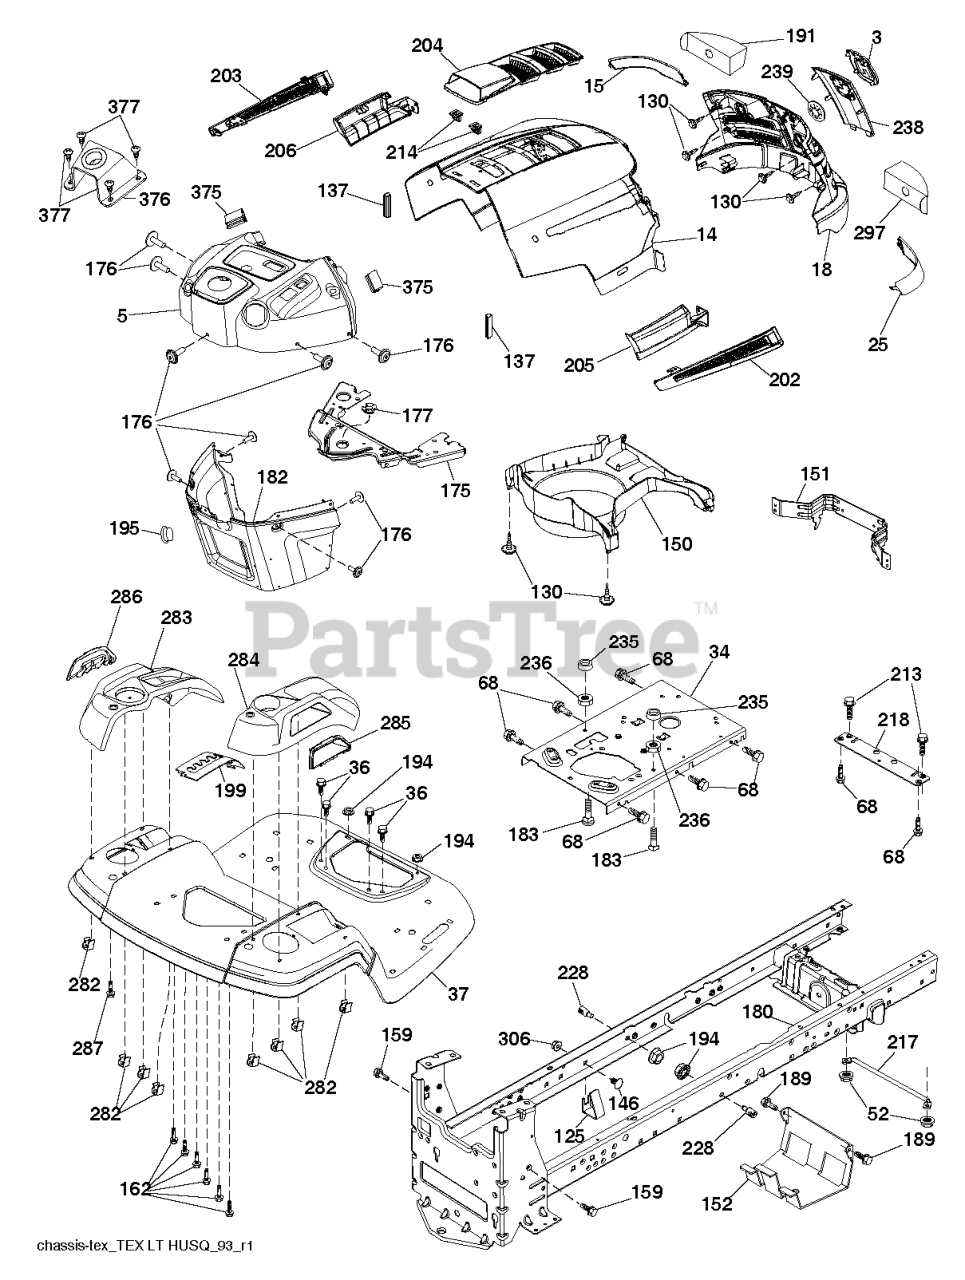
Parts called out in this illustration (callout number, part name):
3	LOGO.HUSQ.GT.LT.CROWN.H
5	SUBASM.DASH.UPPER.W/BUMPER
14	HOOD.HUSQVARNA.LT.ORANGE
15	LENS.HUSQVARNA LT.RH
18	ASM.GRILLE HUSQVARNA.LT.498
25	LENS.HUSQVARNA LT.RH
34	PLATE.ENGINE.WELDED.CHASSIS
36	SCREW 5/16"
37	FENDER.TLT.FS.W/CUPHLD.ORANGE
125	CLIP.FUEL.LINE
137	BUMPER DASH
146	BOLT.RDHD.SHT.SQNK.3/8-16X5/8
151	BRACKET PIVOT
152	SHIELD.BROWNING.W/TEX
159	SCREW, 3/8-16X3/4
175	CROSSMEMBER
176	SCREW.#10-24X5/8.RN.QU
177	BUSHING STEERING
180	CHASSIS
182	DASH.LOWER.PREDATOR LT
189	SCREW
191	INSERT.REFLECTIVE.RH.
195	PLUG.TEX.DASH.SVC.MINDER.GREY
199	PLATE.DECK.LIFT.HUSQ.LT
202	VENT.SIDE.HUSQVARNA.LT.RT
203	VENT.SIDE.HUSQVARNA.LT.LFT
204	SUBASM.TOP.VENT.HUSQ.LT
205	SKIRT.SIDE.HUSQVARNA.LT.RT
206	SKIRT.SIDE.HUSQVARNA.LT.LEFT
213	SCREW HEXAGON HEAD SCREW 5/16-
214	CLIP.RETAINER.TINNER.
217	ROD.PIVOT.HOOD
218	X-PIECE.HOOD.STOP.NON/
228	STUD.W/"D"ANTI-ROTATION
236	NUT.CENTERLOCK.5/16-
238	TRIM.HUSQ LT.668
282	CLIP.RETAINER.CONSOLE.LT.HUSQ
283	CONSOLE.ASM.LFT.RSF.HUSQ.LT
284	CONSOLE CONSOLE.HUSQ.SHIFT.HYD
285	CONSOLE INSERT RH
286	CONSOLE.INSRT.LH.HUSQ.LT.BLACK
287	SCREW 1/4X20
297	INSERT REFLECTIVE
306	NUT LOCK FLG 3/8-16 UNC
375	BUMPER CLIP-ON. DASH 1"
376	MOUNT.ASM.HUSLT.UPPER.STRNG
377	SCREW 10 X 1/2 ZN PL PHIL PAN
